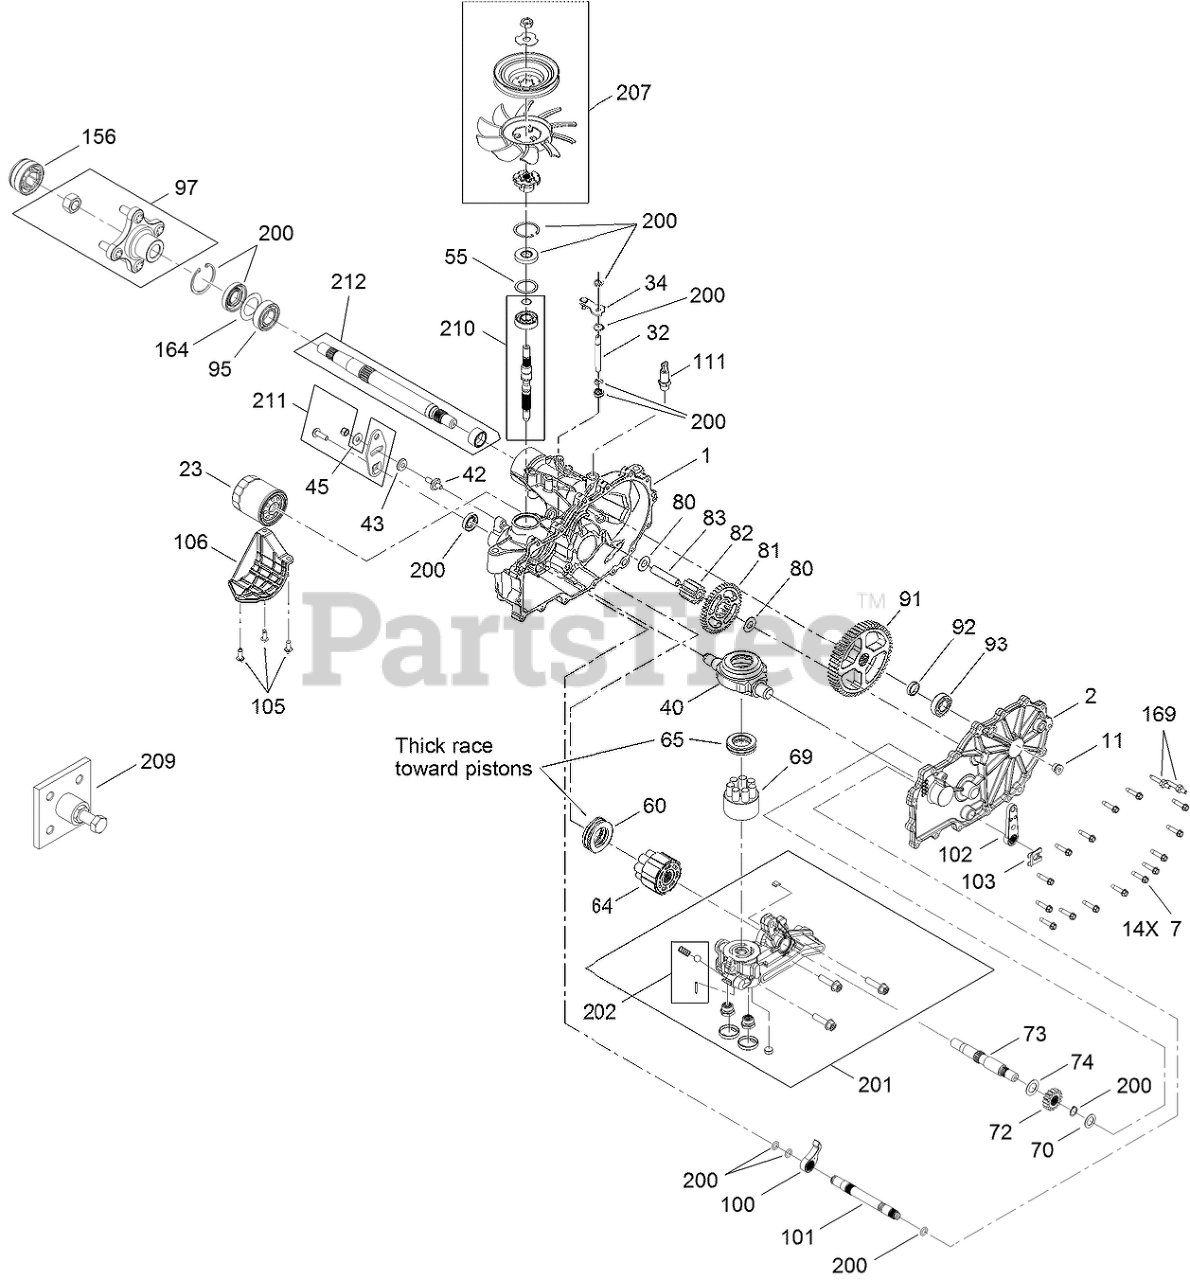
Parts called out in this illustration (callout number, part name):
1	MAIN HOUSING KIT
2	RH HOUSING SIDE KIT
7	SCREW-HHF
11	PLUG-THREAD, STRAIGHT
23	ELEMENT-OIL FILTER, HYD
32	ROD-BYPASS
34	ARM-BYPASS
40	SWASHPLATE-TRUNNION
43	PUCK-FRICTION
45	WASHER
55	SPACER
60	BEARING-THRUST
64	MOTOR CYLINDER BLOCK KIT
65	BEARING-THRUST
69	PUMP BLOCK ASM
70	WASHER-FLAT
72	GEAR-16T
73	SHAFT-MOTOR
74	WASHER
80	WASHER
81	GEAR-43T
82	GEAR-11T
83	PIN-JACKSHAFT
91	GEAR-54T
92	SPACER
93	BEARING-BALL
95	BEARING-BALL
97	HUB KIT
100	PAWL-BRAKE
101	SHAFT-BRAKE, INBOARD
102	HANDLE-BRAKE
103	CLIP-RETAINING
106	GUARD-FILTER, RH
111	ADAPTER-STRAIGHT
156	COVER-NUT, AXLE
164	SPACER
200	SEAL KIT
201	RH CENTER SECTION KIT
202	CHARGE RELIEF KIT
207	FAN PULLEY KIT
209	PULLER-HUB, 4 BOLT
210	INPUT SHAFT KIT
211	CONTROL ARM KIT
212	AXLE SHAFT KIT
